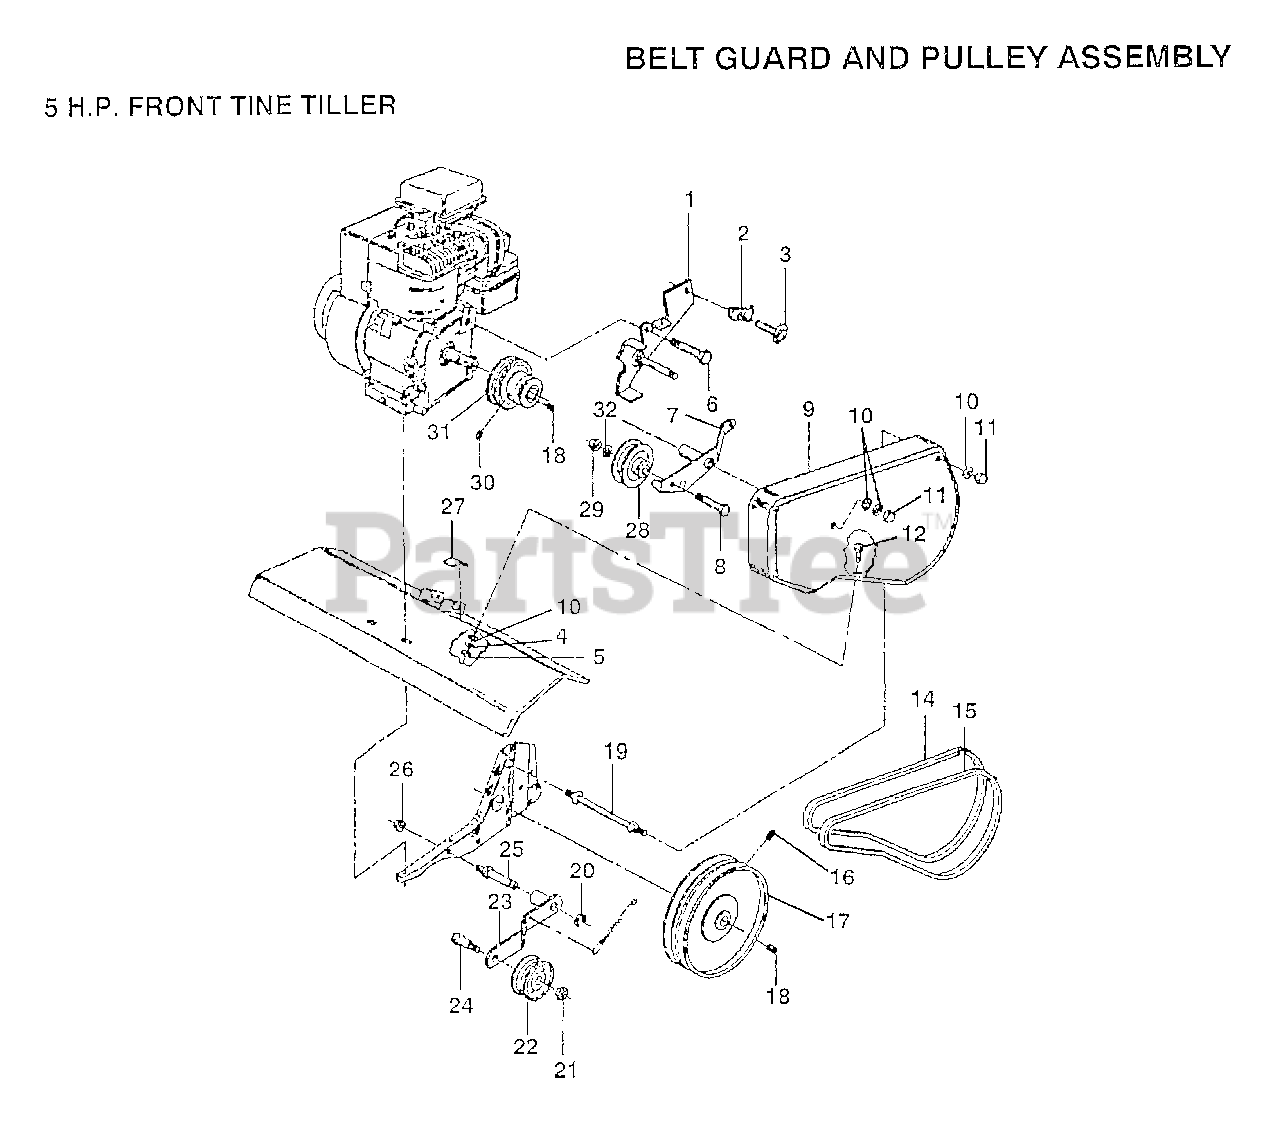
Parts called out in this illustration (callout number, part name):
2	CONDIUT CLIP T
4	LOCKWASHER
7	REV IDLER ARM TI
10	WASHER
11	NUT-CAP TI
12	BOLT T
16	SET SCREW
18	KEY T
19	BOLT TI
20	KLIP RING TI
21	NUT
23	IDLER ARM TI
25	SHAFT IDLER TI
26	JAM NUT TI
27	PAD IDLER TI
28	PULLEY W/SPACER
29	NUT.HEX.3/8-16UNC
30	SET SCREW
31	ENGINE PULLEY TI
32	WASHER
